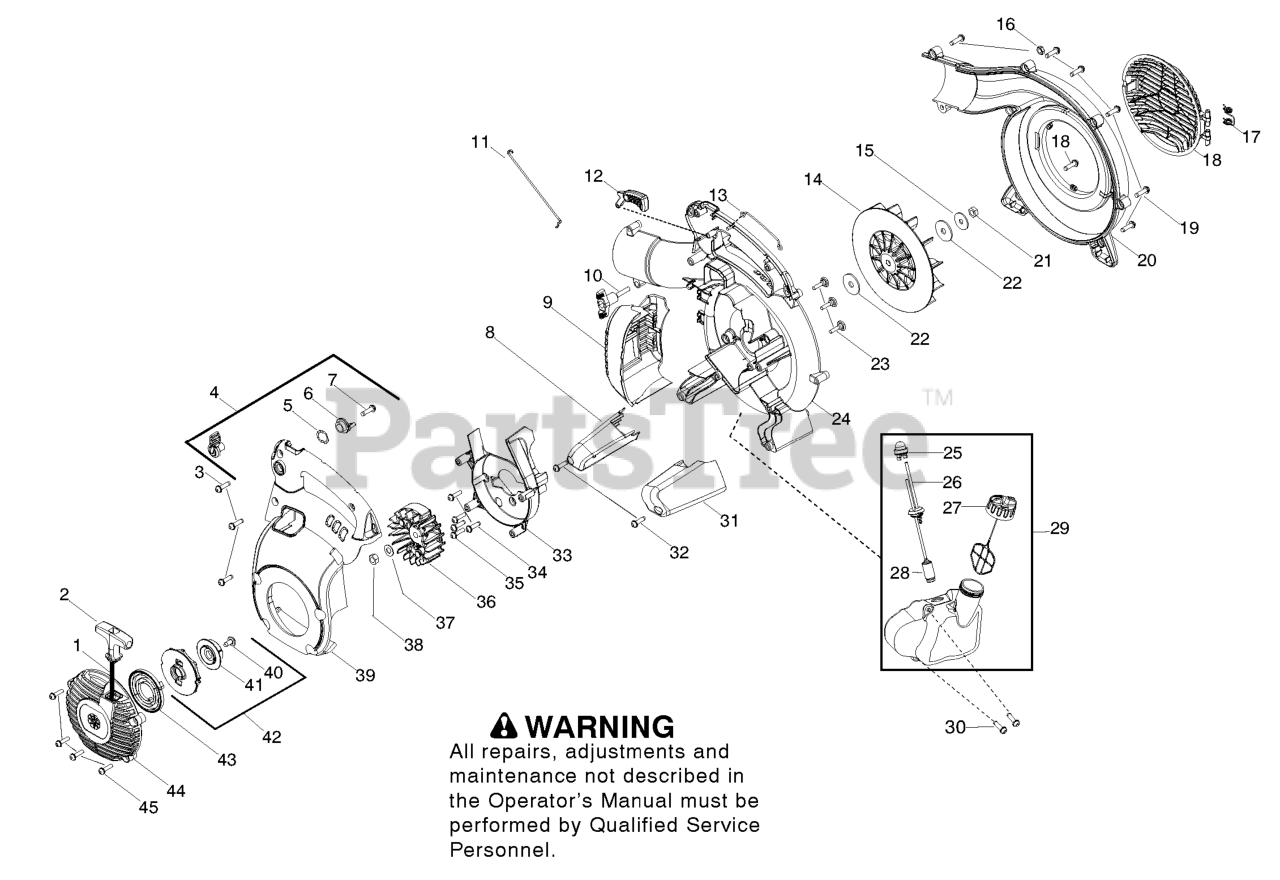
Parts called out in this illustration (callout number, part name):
2	STARTER HANDLE
4	KIT CRUISE CONTROL
5	WAVE WASHER
6	RATCHET CRUISE CONTROL
8	FOOT, FRONT IMPACT
9	ASSY, MUFFLER GUARD
10	ASSY, BLOWER KNOB
11	WIRE LINKAGE
12	TRIGGER, THROTTLE
13	WIRE, HANDLE GROUND
14	IMPELLER
15	WASHER-FLYWHEEL
17	SPRING, VAC DOOR
18	COVER VAC DOOR
20	ASSEMBLY OUTER SCROLL
21	NUT, IMPELLER
22	WASHER IMPELLER
23	SCREW FUEL TANK RETAINER
24	SCROLL, INNER
26	KIT FUEL LINE GROMMET
27	ASSY-CAP W/RETAINER
28	FUEL PICK-UP ASSY
29	ASSY, FUEL TANK
31	FOOT, REAR IMPACT
33	Scroll - Flywheel
35	SCREW - SHROUD
36	ASSY, FLYWHEEL
37	WASHER FLAT
38	NUT-FLYWHEEL
39	COVER, MOTOR HOUSING
42	KIT - STARTER
43	SPRING STARTER
44	HOUSING - STARTER COVER
45	SCREW - SHROUD
